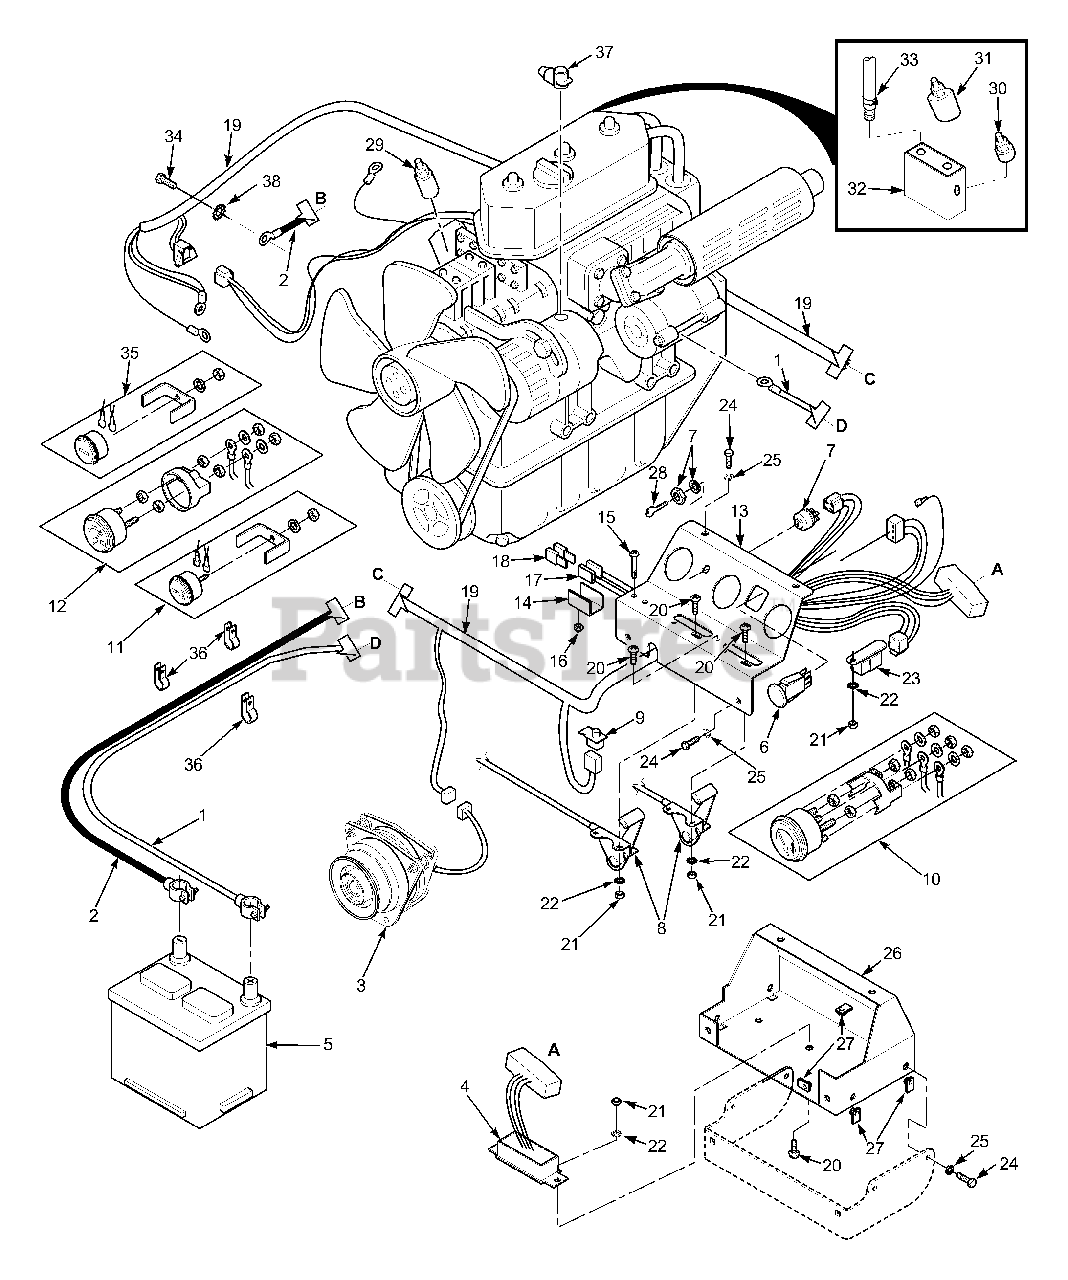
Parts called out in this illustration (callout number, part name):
1	Cable, Positive Battery
2	Cable, Negative Battery
3	Clutch, Electric PTO
4	Module, Interlock
5	Battery (Not Avail. through Scag, Exide P/N 26R)
6	Switch, PTO
7	Switch, Key
8	Cable, Control (Throttle, Choke)
9	Switch, Seat
10	Gauge, Water Temperature
11	Gauge, Oil Pressure
12	Gauge, Volts
13	Panel, Instrument Panel
14	Bracket, Fuse Holder
15	Screw, #10-32 x 1.5" Phillips
16	Nut, #10-32 Elastic Stop
17	Fuse Holder w/ 20 Amp Fuse
18	Fuse, 20 Amp
19	Harness, Wiring
20	Screw, #10-32 x .5" Phillips
21	Nut, Hex #10-32
22	Lock Washer #10
23	Relay
24	Bolt, Hex Head 1/4-20 x .75"
25	Lock Washer 1/4"
26	Base, Instrument Panel
27	U-Nut, 1/4-20
28	Key & Ring Assembly
29	Sender Unit, Water Temperature
30	Switch, Low Oil Pressure
31	Sender Unit, Oil Pressure
32	Manifold, Oil
33	Hose, Oil Pressure Sender
34	Bolt, Hex Head M8-1.25 x 14
35	Hour Meter
36	Clamp, Cable .5" ID
37	Boot, Positive Battery Terminal
38	Washer, Star
